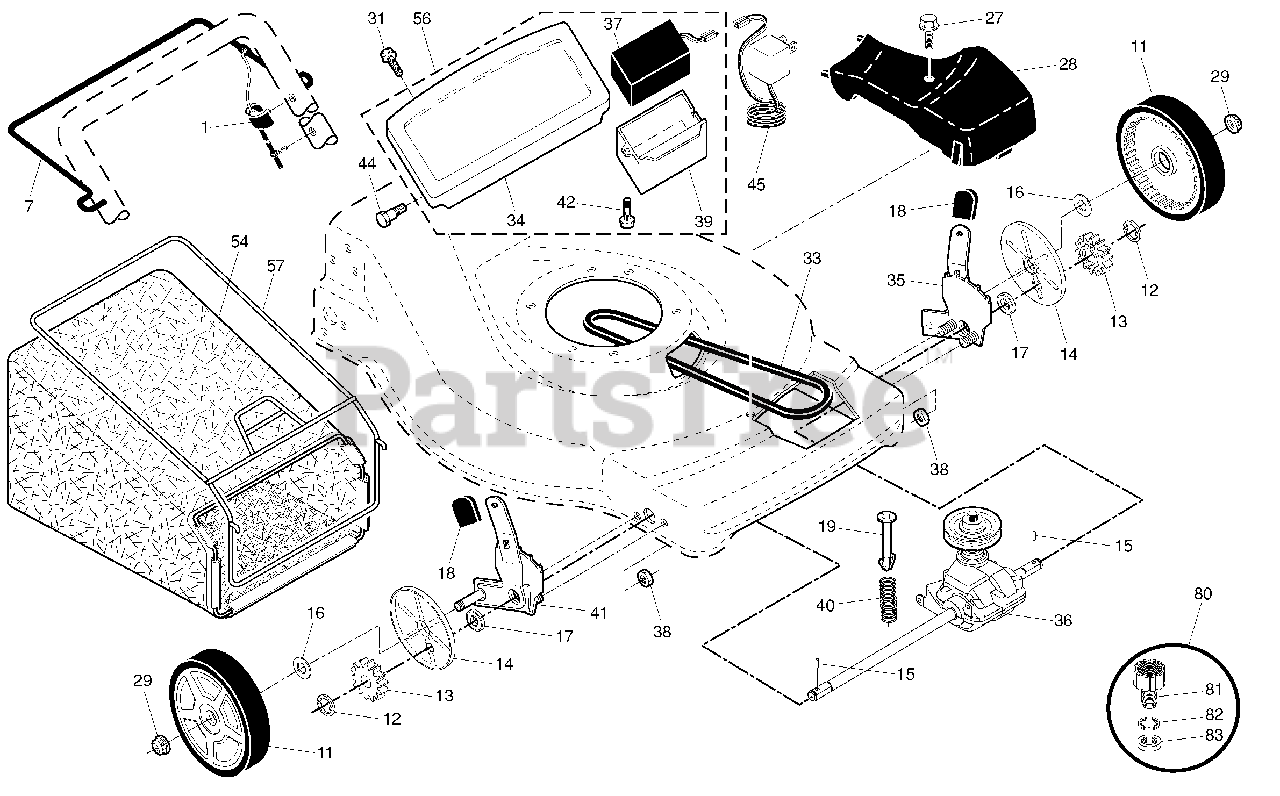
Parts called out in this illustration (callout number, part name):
1	Drive Control Assembly
7	Bar, Drive Control
11	Wheel & Tire Assembly, Front
12	E-Ring
13	Pinion
14	Dust Cover
15	Pawl, Drive
16	Washer, Flat 3/8
17	Bearing, Wheel Adjuster
18	Selector Knob
19	Retainer, Spring
27	Pan Head Tapping Screw #10-24 x 2-3/4
28	Drive Cover
29	Locknut, Hex
31	Screw, Trimplate
34	Trimplate
35	Kit, Wheel Adjuster, LH
36	Gear Case Assembly, Complete
37	Battery
38	Locknut 1/4-20
39	Battery Box
40	Spring
41	Kit, Wheel Adjuster, RH
42	Screw, Battery Box
44	Screw, Trimplate
45	Charger, Battery
54	Grassbag Assembly
56	Trimplate/Battery Box/Battery Assembly
57	Frame, Grassbag
80	Water Washout Assembly
81	Fitting, Hose, Water Washout
82	Washer, Lock, Internal Tooth
83	Locknut, Hex, with O-Ring
